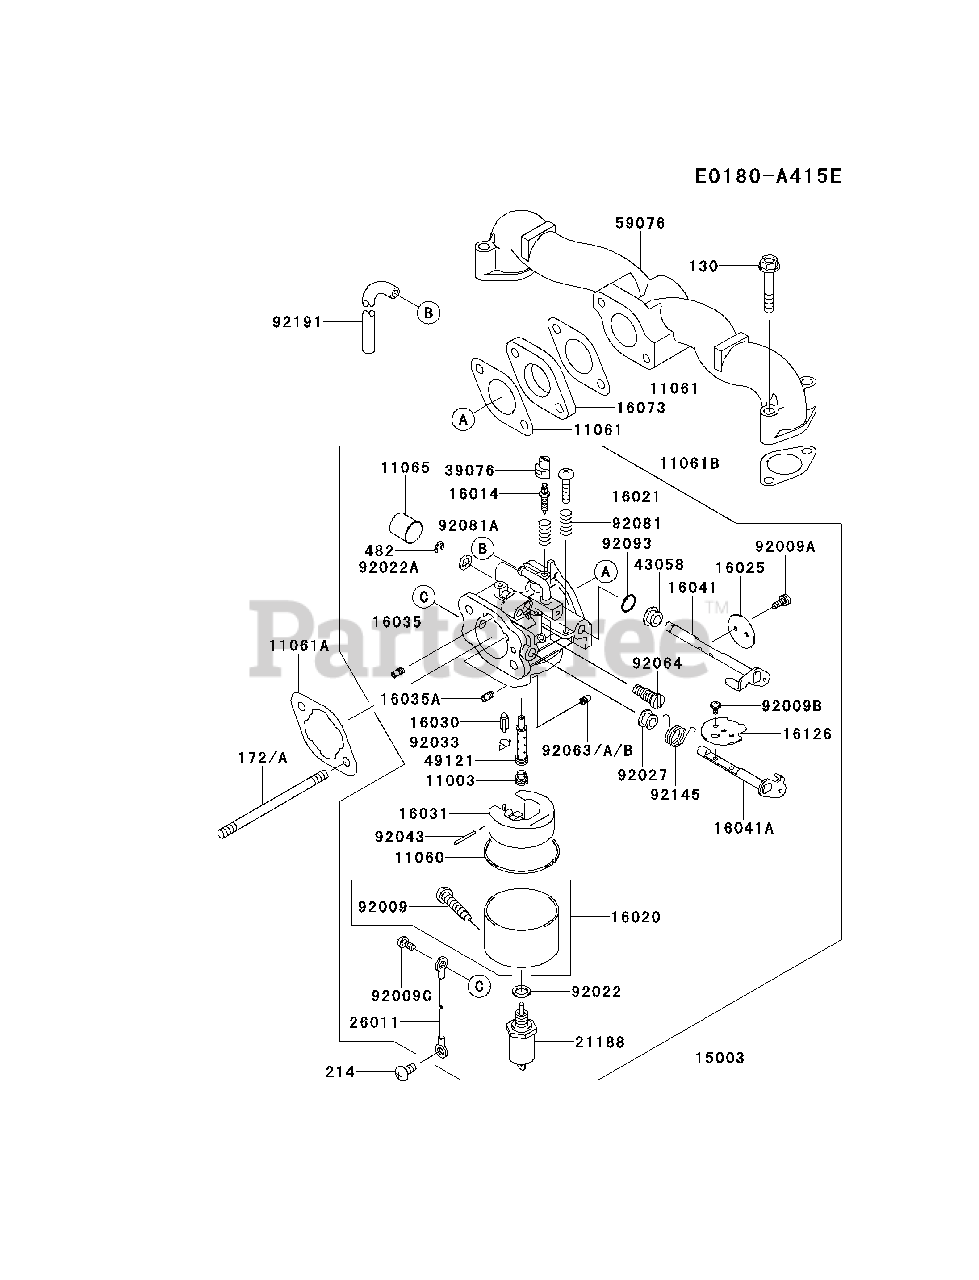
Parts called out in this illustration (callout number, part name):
130	BOLT-FLANGED,6X35
172A	BOLT-STUD,6X85
214	SCREW-PAN+-,5X10
482	CIRCLIP-TYPE-E,4MM
92191	TUBE,4.76X7.94X225
